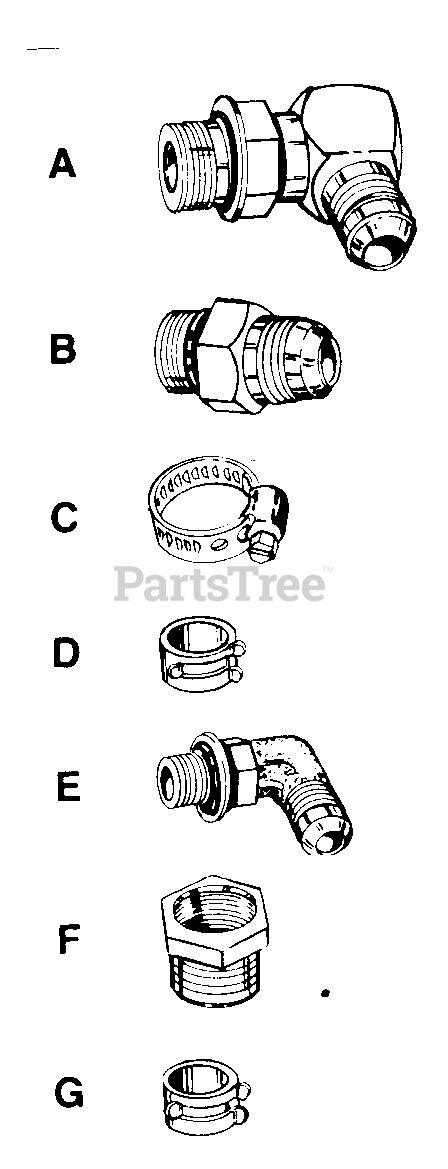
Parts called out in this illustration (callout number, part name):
A	7./8-14 SAE Boss to 3/4-16 JIC.
B	Adapater-"O"-Ring, Boss to Male JIC.
C	Hose Clamp .406 Dia. for Ref. No. 9
D	Hose Clamp 3/8" Dia.
E	1/2-20 SAE Boss to 1/2-20 JIC.
F	Pipe Reducer 1/2-14 to 3/8-18 NPT
G	Hose Clamp .37 Dia. Finish-Green Paint
